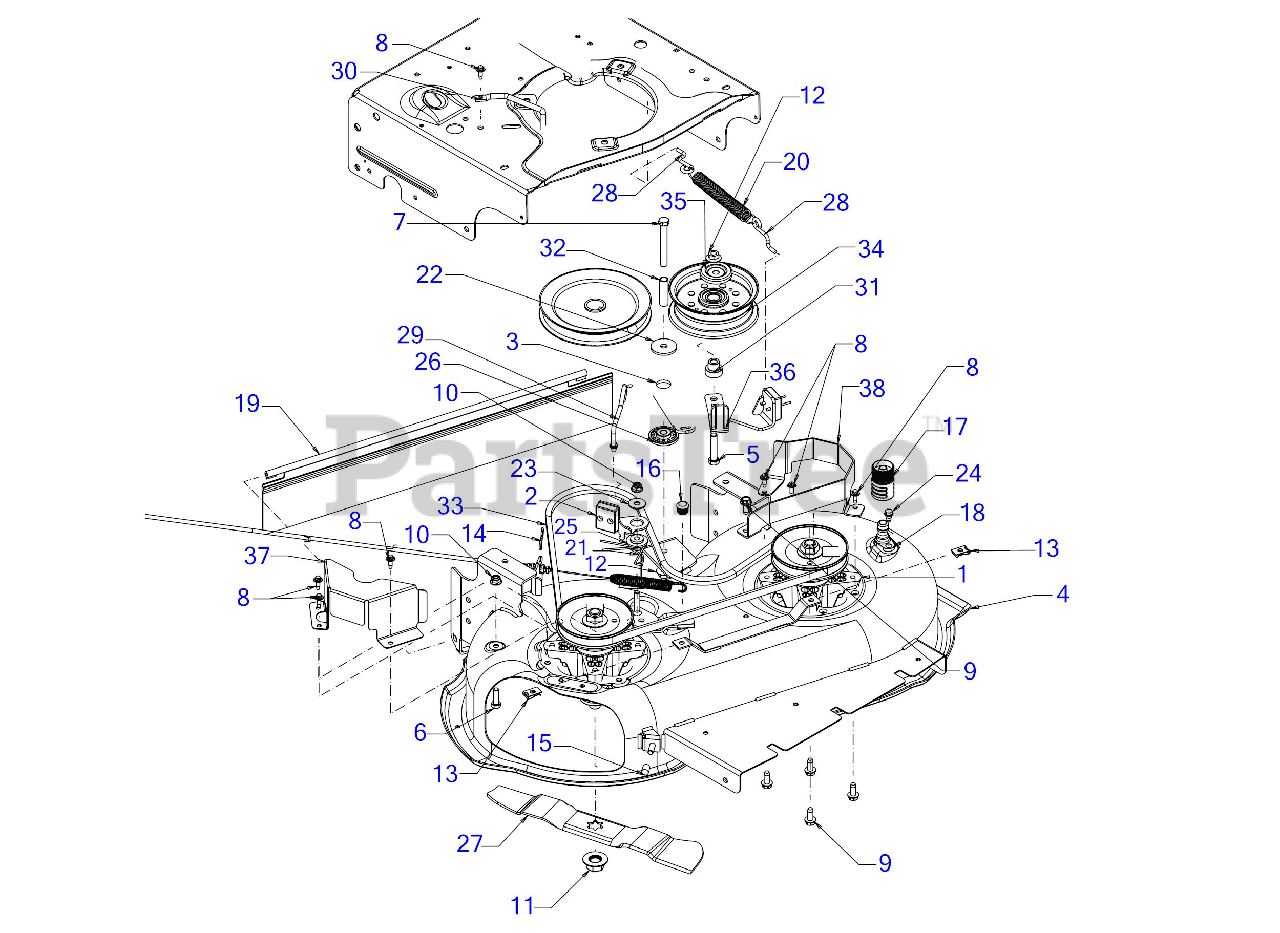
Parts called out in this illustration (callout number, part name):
1	SPINDLE ASM 4.6" DIA
2	DECK BRAKE ASSEMBLY (LH)
3	IDLER PIVOT ASSEMBLY BRACKET
5	HEX SCREW 3/8-16 x 1.75 GR5
6	SCREW 5/16-18 x 1.0 GR5
7	SCREW 3/8-16 x 3 GR8
8	SCREW M6-1 x .625
9	SCREW 5/16-18 x .750
10	FLANGE LOCK NUT 5/16-18
11	HEX NUT
12	FLANGE LOCK NUT
13	U NUT M6-1
14	PIN:COTTER
15	VINYL CAP
16	HANDLE PLUG
17	WATER NOZZLE
18	DECK WASH NOZZLE
19	23.25" TRAIL SHIELD
20	EXTENSION SPRING
21	TORSION SPRING
22	FLAT WASHER .390x1.500x.134
23	FLAT WASHER 344X1.00
24	SHOULDER SCREW 1/4-20 x .50
25	SHOULDER SPACER .750 x .145
26	SHOULDER SPACER
27	14.20" BLADE (MULCH)
28	ROD HOOK
29	DECK BRAKE ROD
30	ENGINE PULLEY BELT KEEPER ROD
31	SHOULDER SPACER
32	SPACER
33	28" MOWER DECK BELT
34	IDLER PULLEY 4.50" DIA
35	IDLER PULLEY CAP
36	BELT KEEPER
